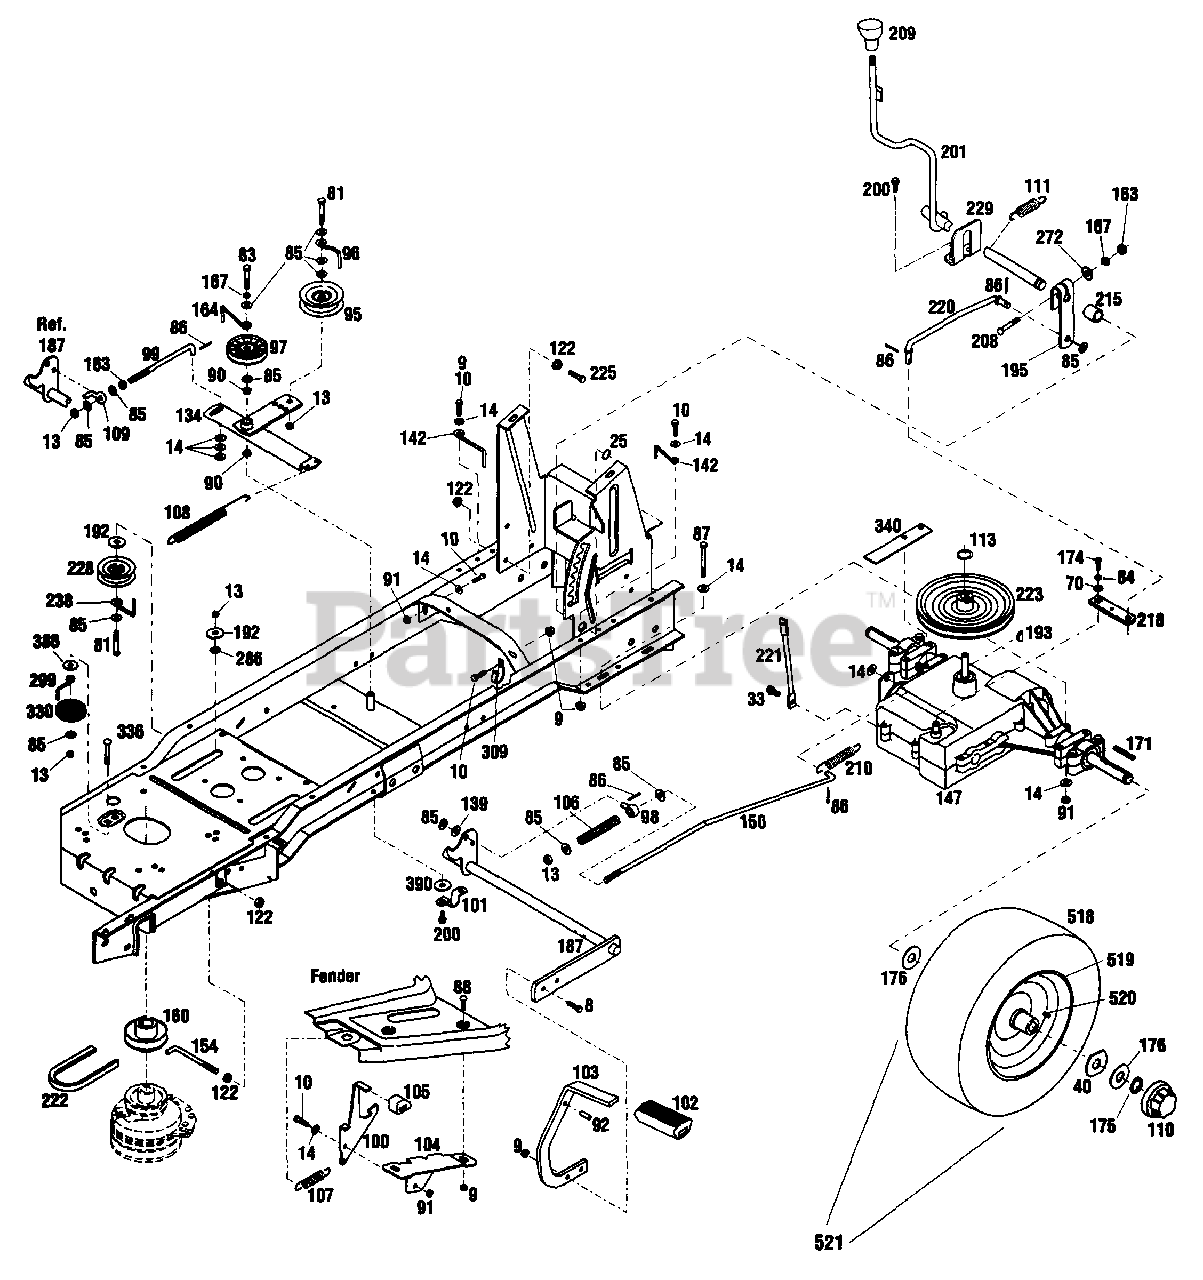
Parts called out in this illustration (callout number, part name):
8	Hex Head Capscrew, 5/16-18 x 1
9	Flange Nut, 5/16-18
10	Hex Head Capscrew, 5/16-18 x 3/4
13	Top Locknut, 3/8-16
14	Flat Washer, 5/16
25	Retaining Ring, 3/4
33	Flange Lock screw, 5/16-18 x 3/4
40	Special Washer, 3/4 x 2-1/2
70	Flat Washer, 1/4
81	Hex Capscrew, 3/8-16 x 2
83	Hex Capscrew, 3/8-16 x 1-3/4
84	Lock Washer, 1/4 SAE
85	Flat Washer, 3/8
86	Cotter Pin, 3/32 x 3/4
87	Hex Screw, 5/16-18 x 2-3/4
88	Carriage Bolt, 5/16-18 x 5/8
90	Nyliner Bushing
91	Locknut, 5/16-18
92	Drive Pin, 5/16 x 1
95	Idler Pulley
96	Belt Guide
97	Idler Pulley
99	Clutch Rod
100	Brake Lock Latch
101	Clip, 3/4
102	Brake Pedal Pad
103	Brake Pedal
104	Brake Lock Bracket
105	Parking Brake Pedal Pad
106	Compression Spring
107	Extension Spring
108	Extension Spring
109	Pivot Rod
113	Retaining Ring, 5/8
122	Flange Nut, 3/8-16
134	Idler Arm Assembly
139	Flat Washer, 3/8
142	Belt Guide
147	Transaxle, Peerless MST-205 5-Speed
150	Brake Rod
154	Clutch Retainer
160	Engine Sheave
163	Hex Nut, 3/8-16
164	Belt Guide
167	Lock Washer, 3/8
171	Square Key, 3/16
174	Hex Screw, 1/4-28 x 1/2
175	Retaining E-Ring, 5/8
176	Flat Washer, 3/4 x 1-7/8
187	Brake Pedal Assembly
192	Flat Washer
193	Woodruff Key, 3/16 x 3/4
195	Shift Shaft Arm
200	Flange Lock screw, 5/16-18 x 3/4
201	Gear Shift Arm
208	Carriage Bolt, 3/8-16 x 2-1/4
210	Extension Spring
218	Transmission Arm
220	Adjusting Rod
221	Transmission Support
223	Transmission Sheave
225	Screw, 3/8-16 x 1-1/4
228	Idler Pulley
229	Shaft Guide
238	Belt Guide
272	Special Washer, 3/8
286	Flat Washer
299	Belt Guide
330	Idler Sheave
336	Carriage Bolt, 3/8-16 x 1-3/4
386	Flat Washer, 1/2
390	Flat Washer, 3/8
518	Tire, 20 x 8.00-8
519	Rim, 10.0 x 6.0
520	Valve Stem
521	Wheel Assembly Complete
